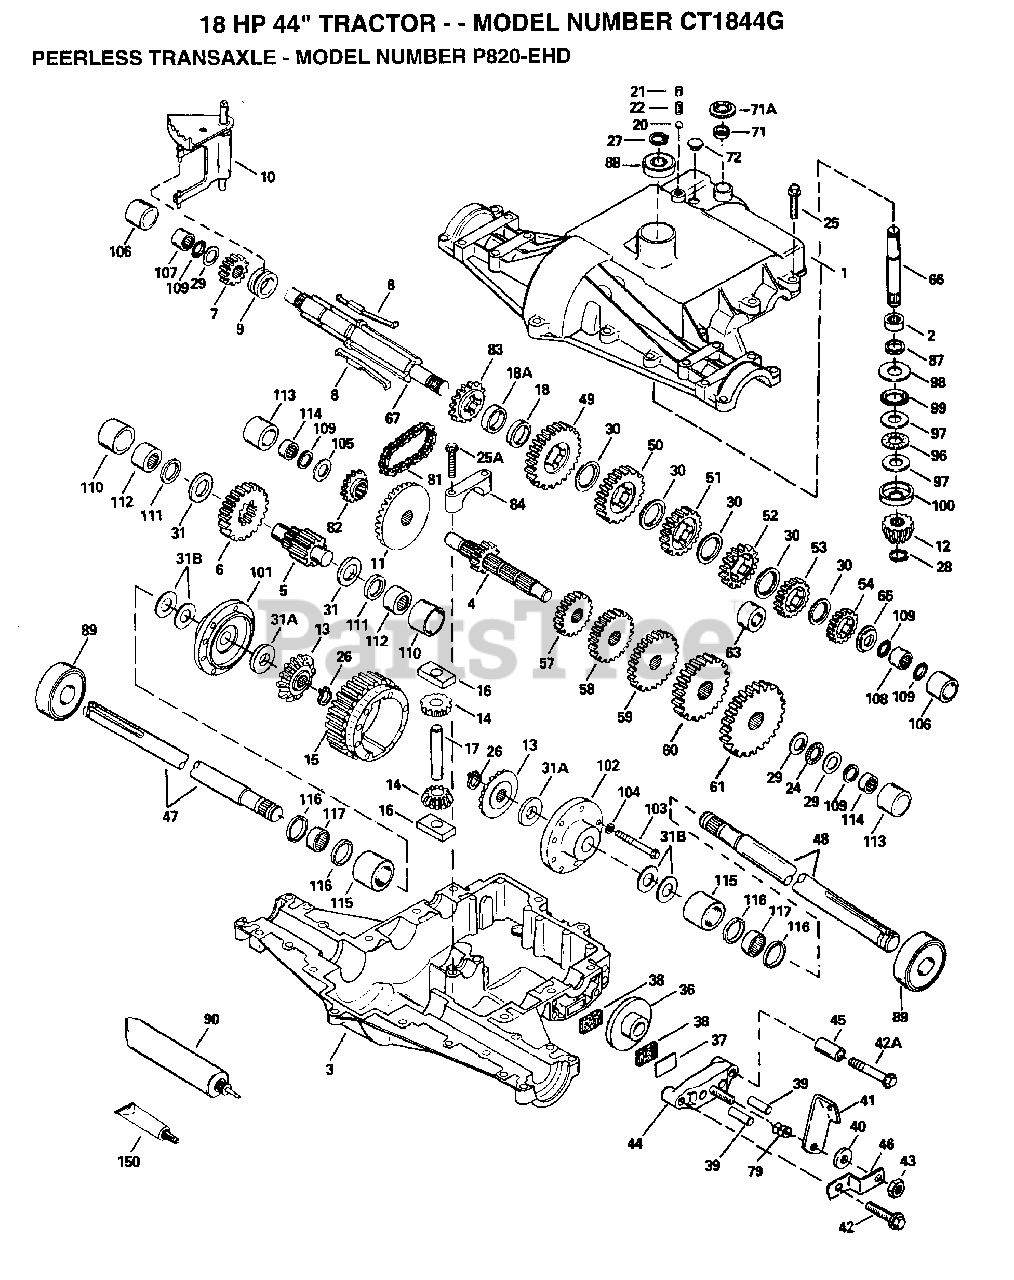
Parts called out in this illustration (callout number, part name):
1	COVER TRANSAXLE
2	BEARING NEEDLE
3	CASE TRANSAXLE
4	SHAFT COUNTER
5	SHAFT, OUTPUT, 9T
6	GEAR, OUTPUT, 35T
7	GEAR, SPUR, 15T
9	COLLAR SHIFT
10	ROD AND FORK ASSY SHIFT
11	GEAR BEVEL, 33T
12	BEVEL PINION, 13T
14	PINION, 10T
15	GEAR, RING, 31T
16	BLOCK DRIVE
18	SPACER, .350/.340 THICK
18A	SPACER, .276/.268 THICK
20	BALL STEEL, 5/16" DIA.
21	SCREW, 3/8-16 X 3/8"
24	THRUST BEARING
25	SCREW HEX HD 5/16-18 X 1-1/4
25A	SCREW, 1/4-20 X 1-1/4
28	RETAINING RING
29	WASHER THRUST
30	WASHER THRUST
31	WASHER THRUST
31B	WASHER THRUST
37	PLATE BRAKE PAD
41	LEVER BRAKE
42	SCREW, 1/4-20 X 1-1/4
42A	SCREW, 1/4-20 X 2-1/4
43	LOCKNUT 5/16-24
44	HOLDER BRAKE PAD
46	BRKT BRAKE LEVER
47	AXLE, 12-5/16" LONG
48	AXLE, 16-3/16" LONG
49	GEAR, SPUR, 41T
50	GEAR, SPUR, 35T
51	GEAR, SPUR, 30T
52	GEAR, SPUR, 25T
53	GEAR, SPUR, 22T
54	GEAR, SPUR, 19T
57	GEAR, SPUR, 15T
58	GEAR, SPUR, 20T
59	GEAR, SPUR, 25T
60	GEAR, SPUR, 28T
61	GEAR, SPUR, 31T
66	SHAFT INPUT
67	SHAFT BRAKE
71	SEAL SQUARE CUT
72	PLUG, THRDED, 9/16-18
81	CHAIN, ROLLER
82	SPROCKET 9T
83	SPROCKET 18T (REV)
84	BEARING CAP
87	OIL SEAL 3/4
88	BEARING BALL
89	BEARING BALL
90	GREASE BENTONITE, 32 OZ.
96	BEARING THRUST
97	WASHER THRUST
100	WASHER CUPPED
101	CARRIER DIFF THREADED HOLES
102	CARRIER DIFF
103	SCREW, 1/4-20 X 2-1/4
104	WASHER LOCK 1/4
107	BEARING NEEDLE
108	BEARING NEEDLE
110	SLEEVE STEPPED
111	RING SQ CUT
112	BEARING NEEDLE CAPPED
113	SLEEVE STEPPED
114	BEARING NEEDLE CAPPED
115	SLEEVE STEPPED
116	RING SQ CUT
117	BEARING NEEDLE
150	GASKET ELIMINATOR
